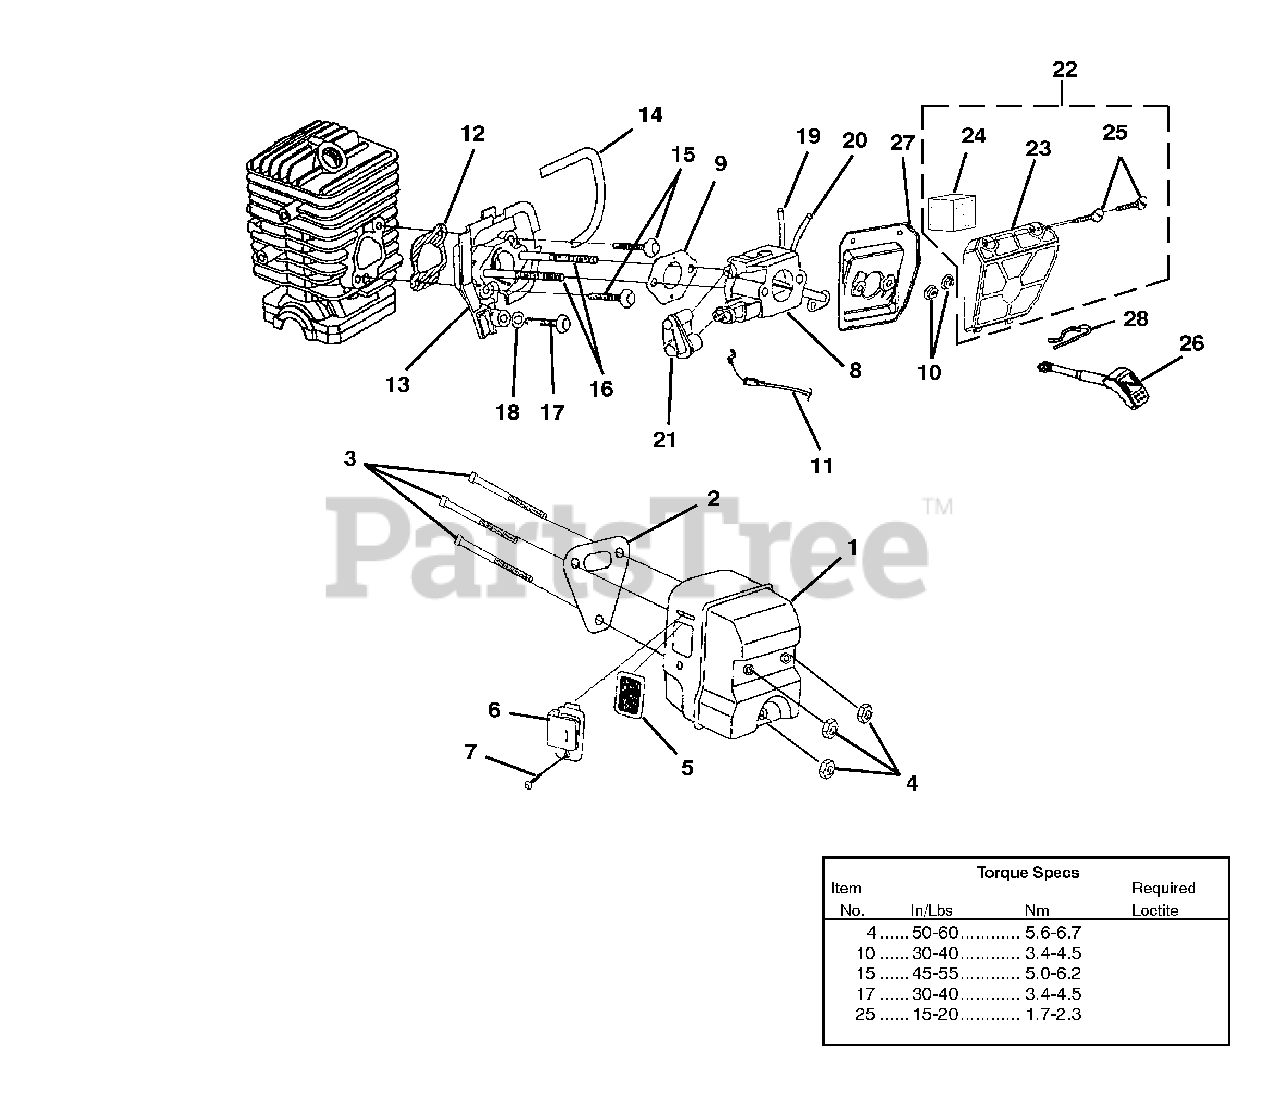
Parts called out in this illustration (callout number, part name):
1	Muffler Kit (45cc)
2	Muffler Gasket
3	Screw-Square Hd.
4	Nut-Locking Hex (10-32)
5	Screen, Spark
6	Deflector, Muffler (45cc)
7	Screw
8	Carburetor Assy (Int'l 45cc)
9	Carburetor Gasket
10	Flange Nut (10-24)
11	Throttle Cable
12	Gasket, Heat Dam
13	Heat Dam
14	Seal, Heat Dam
15	Screw, Truss Hd. Taptite (10-24 x 7/8")
16	Screw, Carburetor
17	Screw, Thread Form (10-14 x 1/2")
18	Washer, Retaining
19	Fuel Line (Tank to Carburetor 8 1/2")
20	Fuel Line (Carburetor to Purge Bulb 4")
21	Carburetor Grommet
22	Air Filter Kit
23	Air Filter Cover
24	Pre Filter (In engine housing)
25	Screw-Slotted Pan Hd. (8-16 x 5/8")
26	Rod, Choke
27	Air Filter Plate
28	Spring Clip (Choke Rod)
